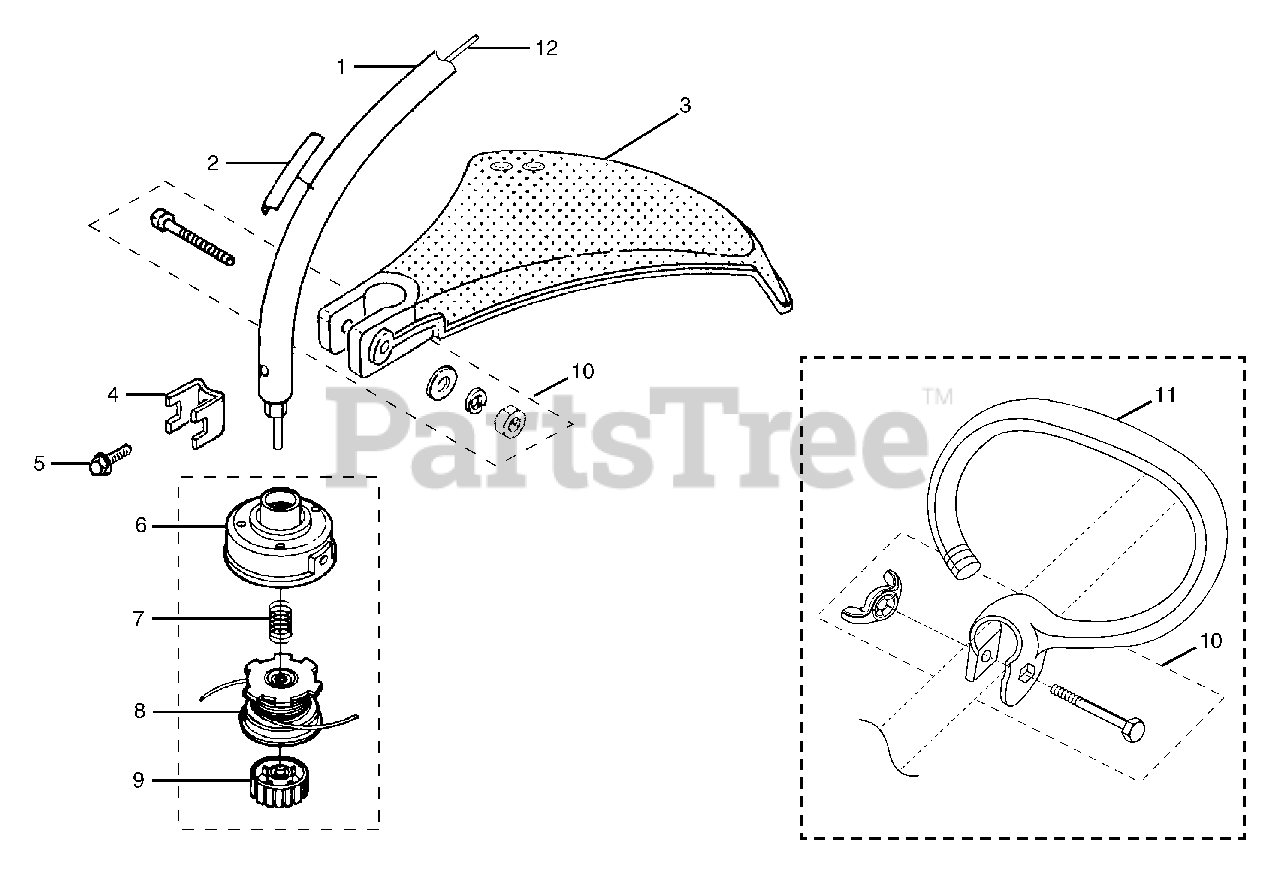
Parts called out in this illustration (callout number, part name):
1	BOOM ASSEMBLY KIT
2	BOOM DECAL (WARNING)
3	GRASS DEFLECTOR
4	CLAMP
5	SCREW
6	HOUSING AND EYELETS
7	COMPRESSION SPRING
8	SPOOL W/LINE (.095 in.)
9	SPOOL RETAINER (RH/THREAD)
10	FASTENER PARTS KIT
11	FRONT HANDLE
12	FLEX SHAFT
